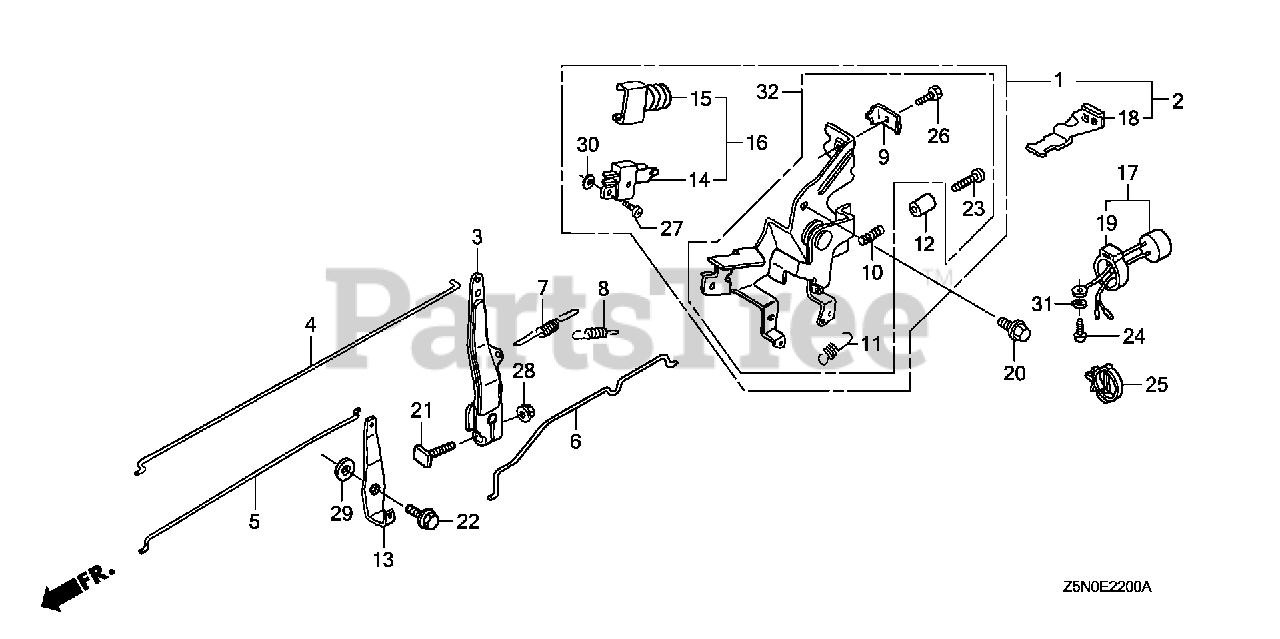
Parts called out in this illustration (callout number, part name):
1	CONTROL ASSY.
3	ARM, GOVERNOR
4	ROD, GOVERNOR
5	ROD, CHOKE
6	ROD, JOINT
7	SPRING, GOVERNOR
8	SPRING, GOVERNOR PRIMARY
9	HOLDER, CABLE
10	SPRING, CONTROL ADJUSTING
11	SPRING, CABLE RETURN
12	COLLAR, STOPPER
13	LEVER, CHOKE JOINT
14	SWITCH ASSY., ENGINE
15	COVER, SWITCH
16	SWITCH ASSY., ENGINE STOP
20	BOLT, FLANGE (6X12) (CT200)
21	BOLT, GOVERNOR ARM
22	BOLT, FLANGE (6MM)
23	SCREW, RECESSED (5X20)
26	BOLT, RECESSED (5X14)
27	SCREW, PAN (4X14)
28	NUT, FLANGE (6MM)
29	WASHER, PLAIN (6MM)
30	WASHER, SPRING (4MM)
